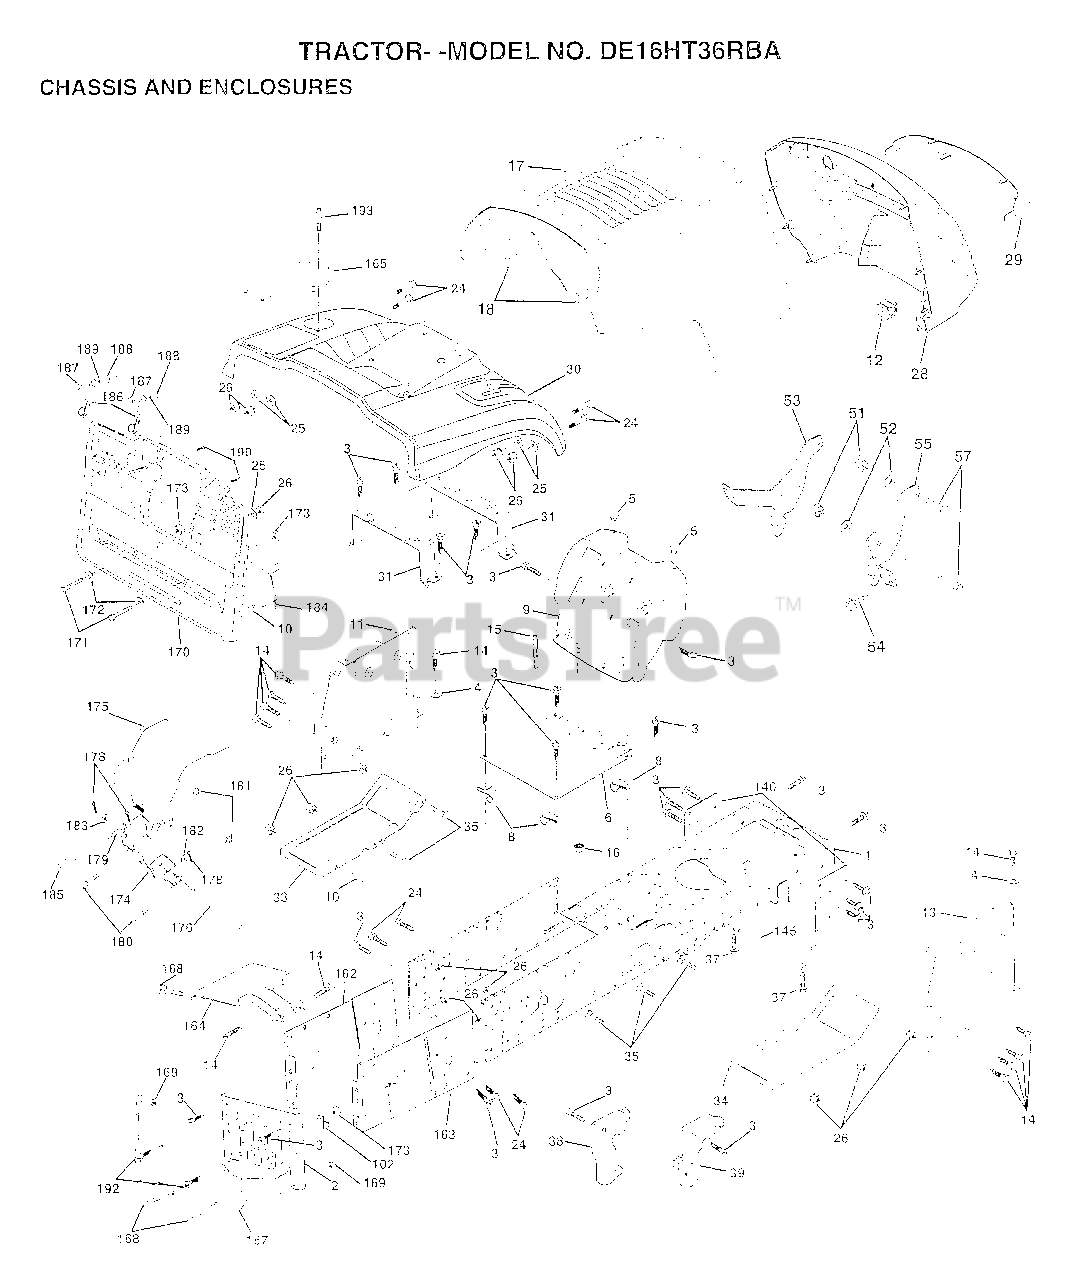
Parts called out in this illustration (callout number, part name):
1	CHASSIS.STAMPING
2	DRAWBAR.CRD
3	SCREW
4	WASHER
5	BUMPER-HOOD/DASH
6	SADDLE
8	"CLIP,INSULATOR"
9	DASH.SILKSCREEN
11	"PANEL-DASH,LH"
12	CLIP.TINNERMAN
14	SCREW LT
15	SCREW
24	BOLT
25	WASHER
26	NUT
28	GRILL
30	FENDER.CRD.SAGE
31	BRKT.SUPT.FENDER.CRD
33	FOOTREST
34	FOOTREST.PNT.RH
35	BOLT
37	SCREW LT
38	BRACKET ASM LH
39	BRACKET ASM RH
51	NUT
52	WASHER
53	BRACKET.GRILLE.LH
54	SCREW.HEX.WS.HD
55	BRACKET.GRILLE.RH
102	CLIP T
140	BRKT SUSPENSION
145	"ROD POVOT,CHASSIS"
162	BRKT.EXT.CHASSIS.LH.CRD
163	BRKT.EXT.CHASSIS.RH.CRD
164	SUPPORT.BATTERY.CRD
165	COVER.BATTERY.CRD.BLACK.LT
167	SUPT.ASM.BACKPLATE
168	BOLT-RD HD SQ NK
170	COVER.BACKPLATE.BLACK
171	BOLT.HEX.3/8-16X2-1/2
173	NUT
174	BRKT.SWITCH.FBI.CRD
175	GRUARD.DOOR.REAR.CRD
176	HINGE PIN
177	SPRING.COVER.LH
179	ROD.PIVOT.FBI.CRD
182	WASHER.385X.625
183	WASHER
184	BRKT.ACTUATOR.BAG.CRD
185	TUBE.LEVER.SWCH.FBI.CRD
186	LATCH ASSY.BAGGER
187	WELDNUT
188	WASHER #10
189	LOCKWASHER
190	SCREW
192	SCREW LT
193	SCREW LT
